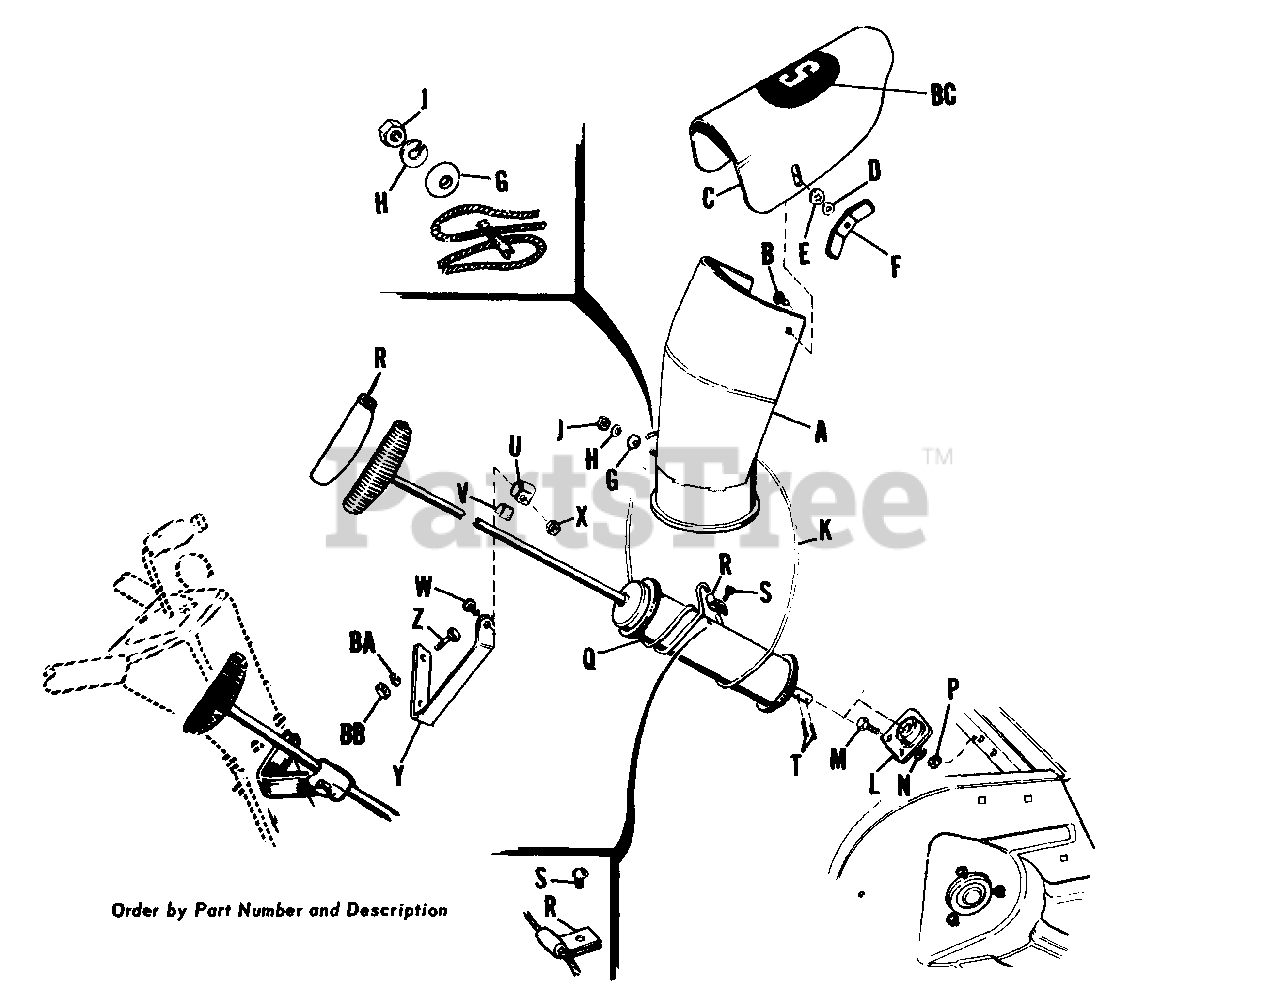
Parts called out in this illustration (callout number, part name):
A	Spout Assembly
B	Carriage Bolt, 5/16"-18 x 3/4" long
C	Spout Extension
D	Plain Washer, 3/8"
E	Lock Washer, 3/8"
F	NUT, Wing, 5/16-18
G	Cup Washer
H	Lock Washer, 5/16"
J	Hex Nut, Full, 5/16"-18
K	Cable Assy.
M	Hex Capscrew, 1/4"-20 x 5/8" long
N	Lock Washer, 1/4"
P	Hex Nut, Full, 1/4"-20
Q	Tube Assembly, Spout Control
R	Cover, Handle
S	Self-Tapping Screws, 1/4"-20 x 3/8"
T	Cotter Pin, 1/8" x 3/4" long
U	Guide Rod
V	Liner, Guide
W	Hex Capscrew, 5/16"-18 x 1-1/4" long
X	Hex Nut, Full, Lock, 5/16"-18 NC
Y	Support, Spout Adj. Rod
Z	Hex Capscrew, 1/4"-20 x 1-3/4" long
BA	Lock Washer, 1/4"
BB	Hex Nut, Full, 1/4"-20
